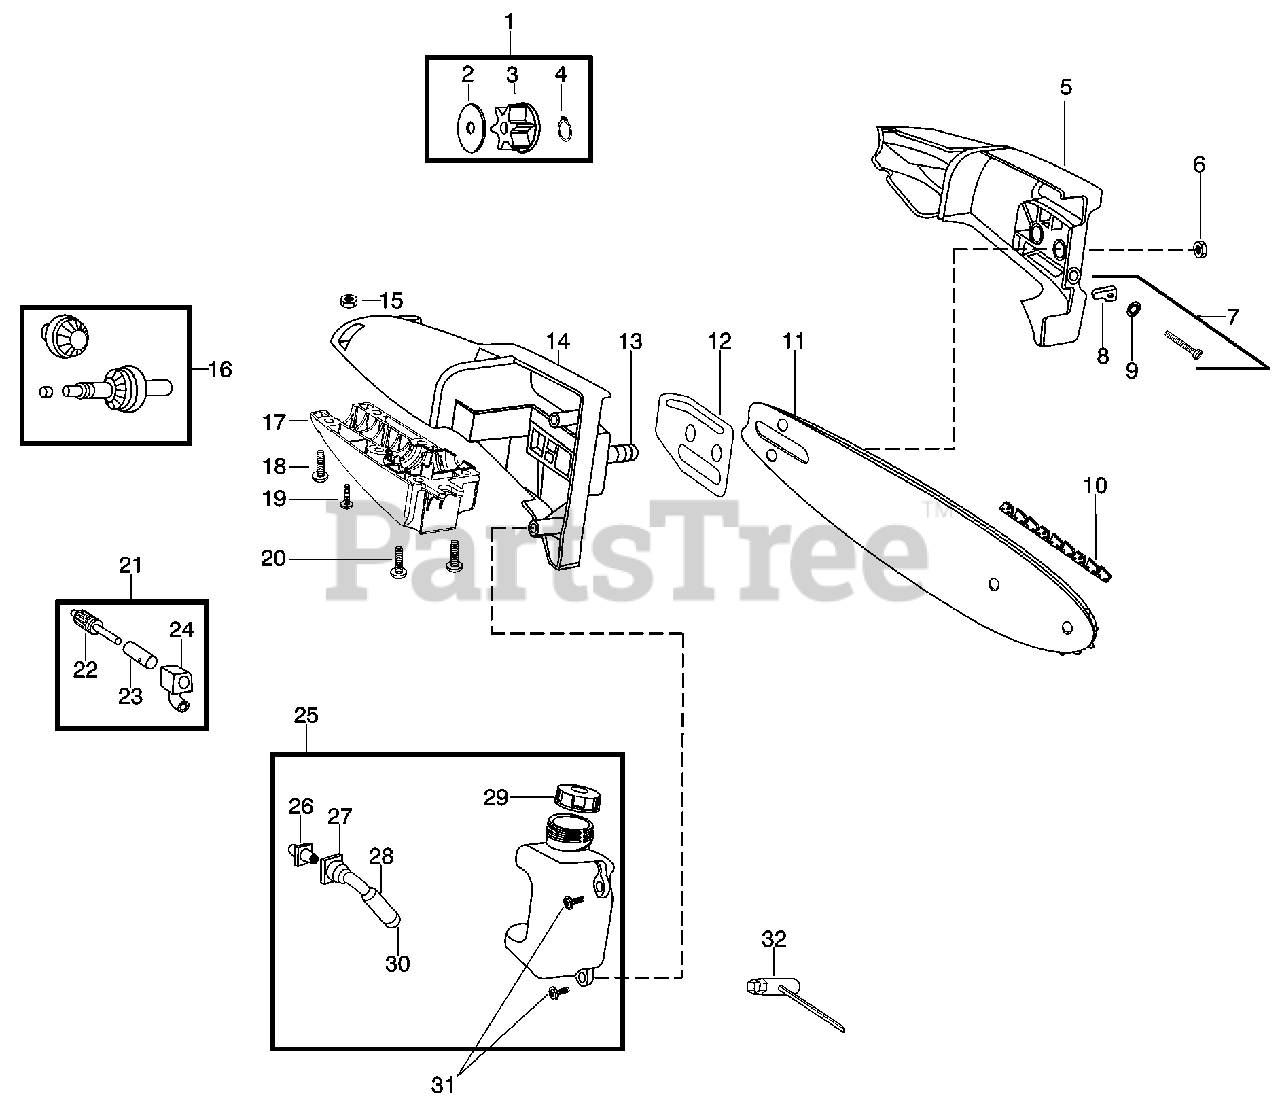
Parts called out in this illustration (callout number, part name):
1	Kit - Sprocket Assy.
3	Sprocket
4	Retainer - Sprocket
5	Assy - Bar Clamp
6	Nut - Bar Mounting
7	Kit - Bar Adjust
8	Pin - Bar Adjust
9	Retainer - Bar Adjust
10	Chain - 8"
11	Bar - 8"
12	Plate - Bar Pad
13	Bolt - Bar
14	Housing - Upper
16	Kit - Gear Assy.
17	Housing - Lower
18	Screw (10-24)
19	Screw - Alignment (10-14 x 1/2")
20	Screw (10-14 x 13/16")
21	Kit - Oil Assy
22	Assy. - Gear Plunger
24	Assy- Oil Block
25	Assy - Oil Tank
26	Fitting - Oil Line
27	Intake - Oil Line
28	Filter - Oil
29	Cap - Oil
30	Plug - Oil Filter
31	Screw (10-24 x 7/8")
32	Wrench - Bar
